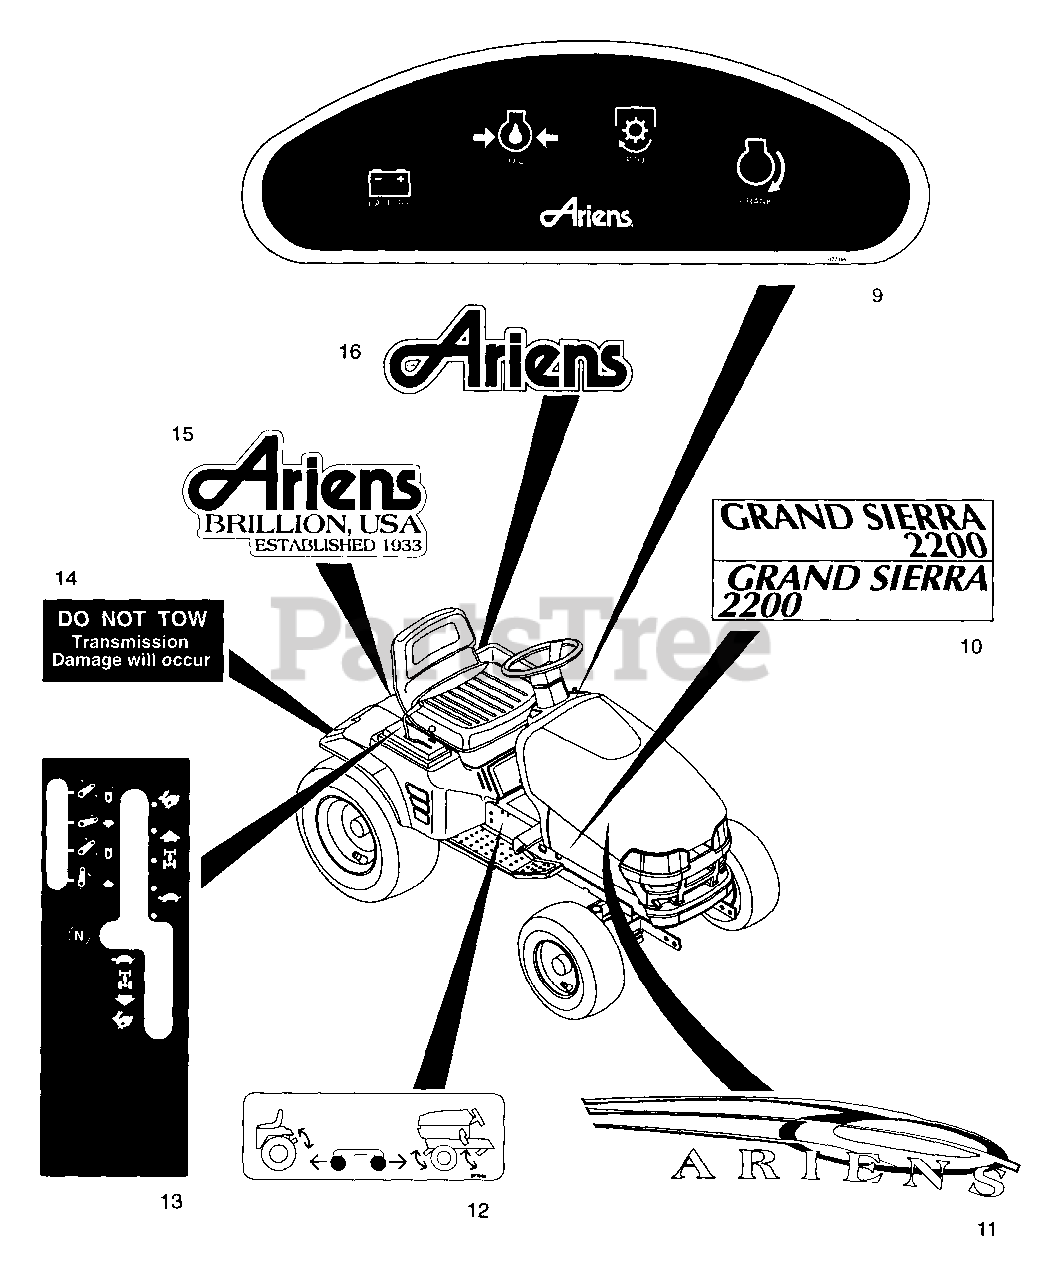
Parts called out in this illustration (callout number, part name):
9	DECAL- DASH W/ LIGHTS
10	DECAL - GRAND SIERRA 2200 - L
11	DECAL- ARIENS HOOD LOGO- R
12	DECAL - LIFT SELECTOR
13	DECAL, CONTROL CONSOLE
14	TRANSMISSION DECAL
15	DECAL- ARIENS EST. 1933
16	DECAL-ARIENS
